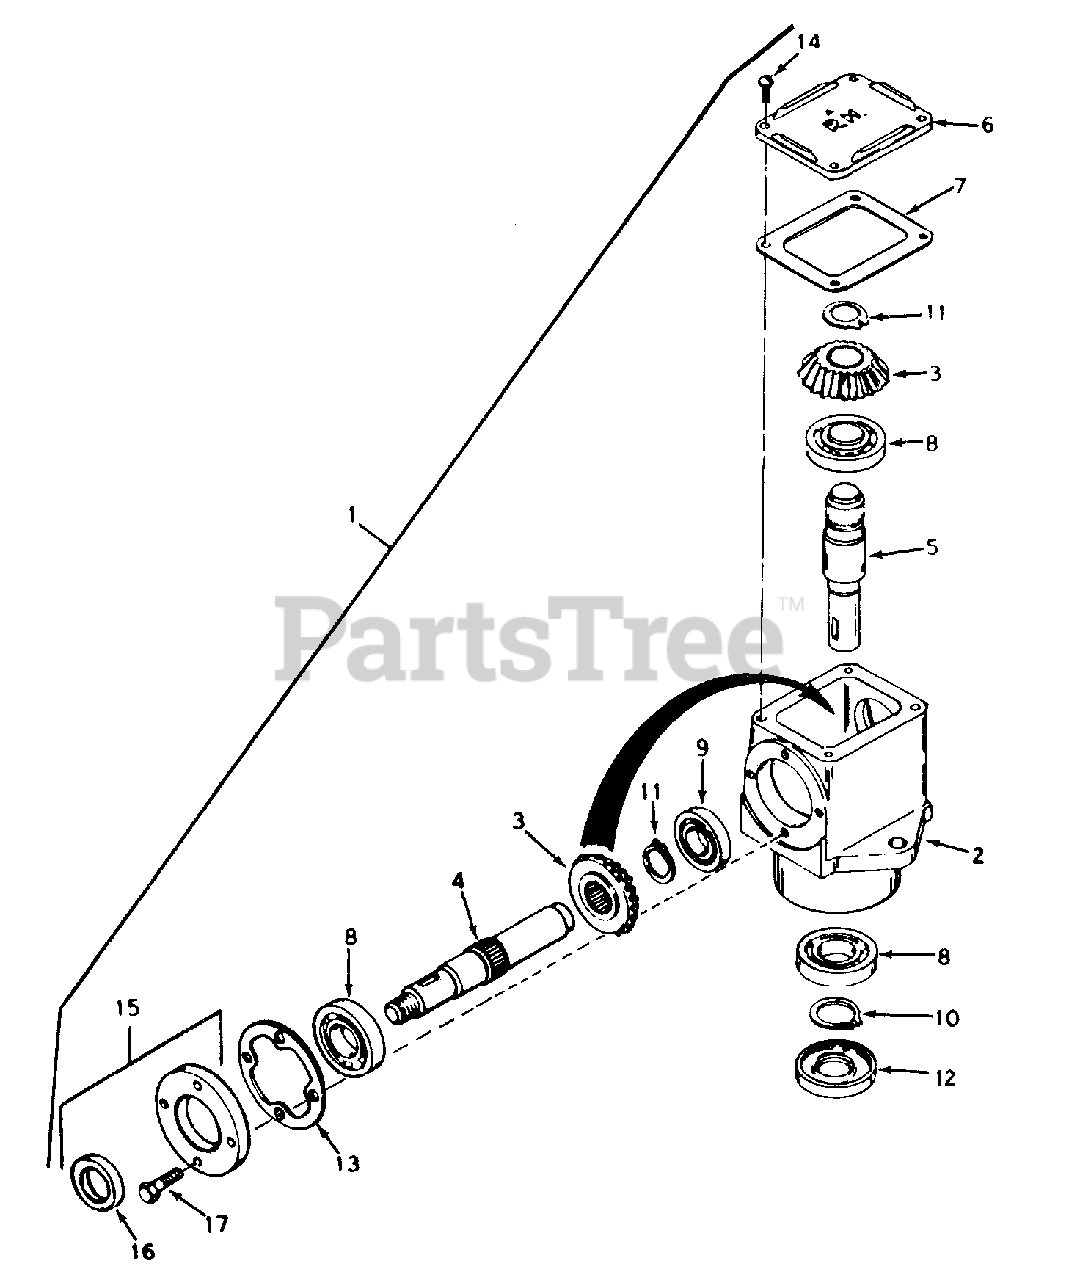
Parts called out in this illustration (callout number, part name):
1	Head Ass'y. R.H.
2	Housing, Right Angle Drive
3	Gear, Miter
4	Shaft, Input
5	Shaft, Output
6	Cover, Right Hand
7	Gasket, Cover
8	Bearing, Ball
9	Bearing, Ball
10	Ring, Snap
11	Ring, Snap
12	Seal, Oil
13	Gasket, Cap
14	Screw, Rd. Hd. Self-Tap. 10-24 x 1/2
15	Cap & Seal Ass'y., Retainer
16	Seal, Oil
17	Screw, Hex Hd. 1/4-20 x 7/8
